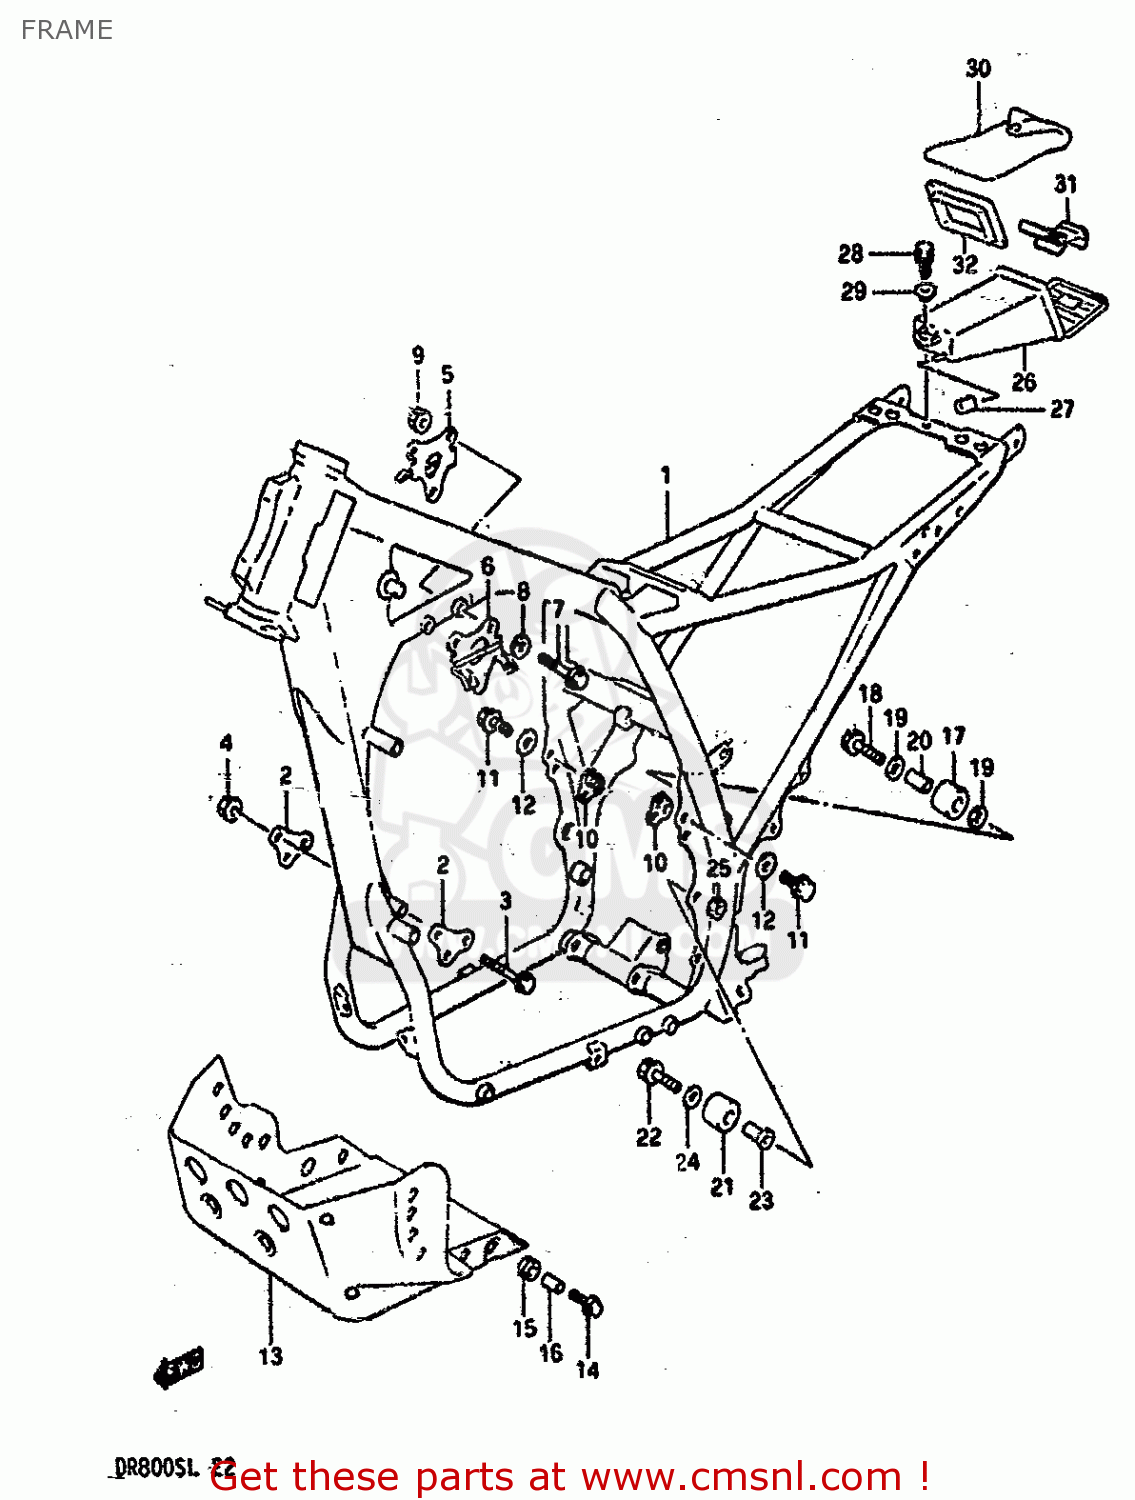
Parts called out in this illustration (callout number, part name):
1	FRAME (WHITE)
2	PLATE,FRONT (WHITE)
3	BOLT 8X70
4	NUT
5	PLATE,UPPER RH (WHITE)
6	PLATE,UPPER LH (WHITE)
7	BOLT,ENGINE MOUNTING (L:55)
8	LOCK WASHER
9	NUT
10	PLATE,REAR (WHITE)
11	BOLT
12	LOCK WASHER
13	PROTECTOR,ENGINE (RED)
14	BOLT(6X20)
15	CUSHION
16	SPACER (6.1X9X9)
17	ROLLER,CHAIN CONTROL
18	BOLT(8X41)
19	WASHER
20	SPACER (8.6X13.8X28)
21	ROLLER,CHAIN CONTROL
22	BOLT(10X52)
23	SPACER,CHAIN ROLLER, LWR
24	WASHER
25	NUT 10MM
26	HOLDER TOOL
27	CUSHION
28	BOLT
29	WASHER
30	TOOL ASSY
31	BAND
32	CUSHION,TOOL HOLDER
